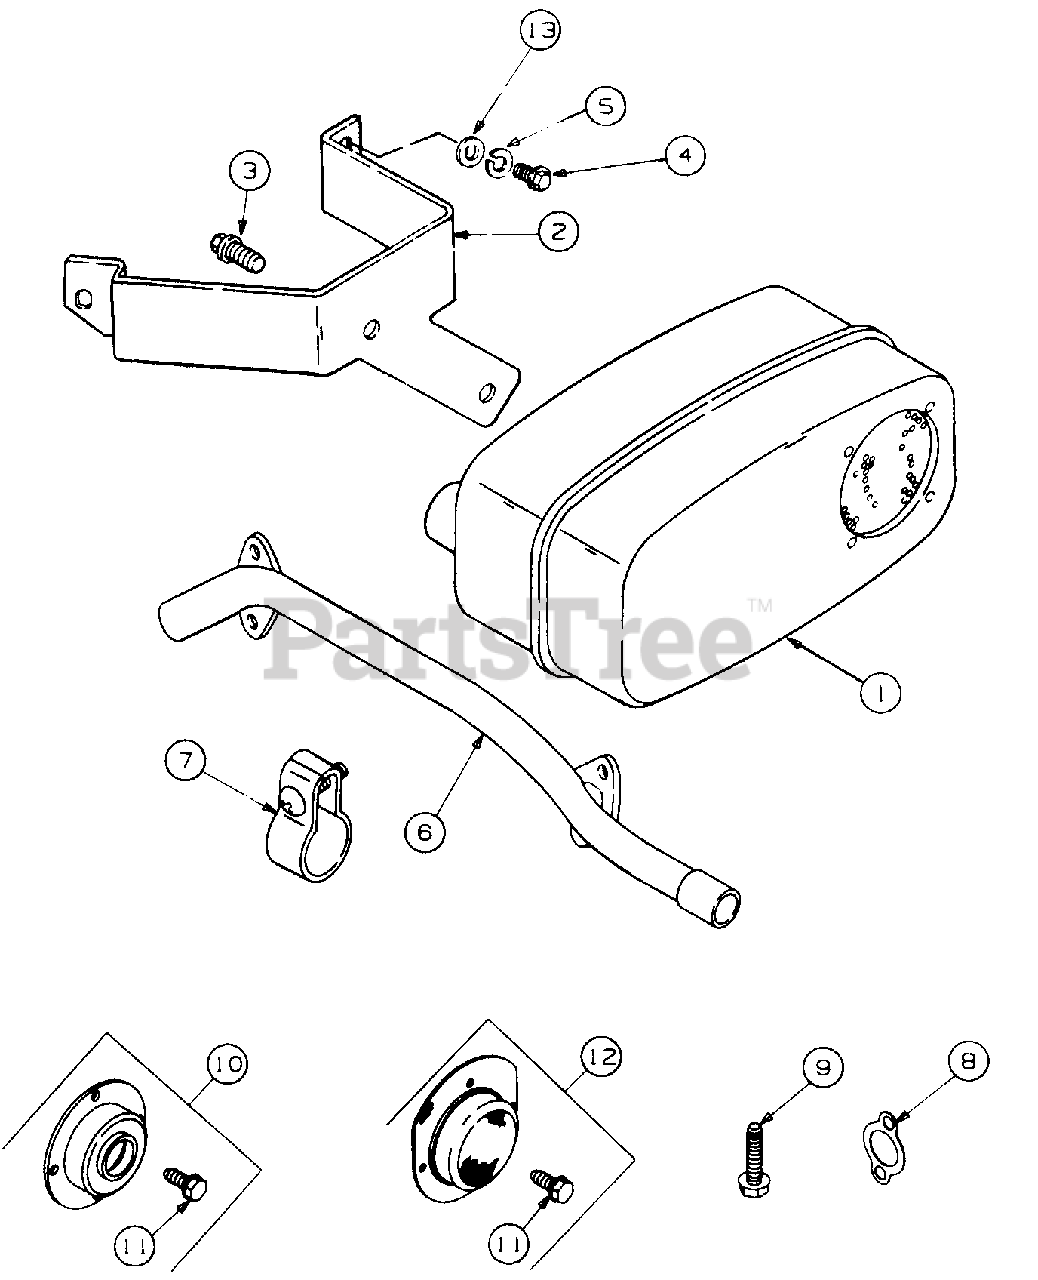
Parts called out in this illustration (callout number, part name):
1	Muffler
2	Bracket, Muffler
3	Screw, Hex Wash Hd Tap, 1/4-20 X .50 Lg
4	Screw, Hex Cap, M6-1.0 X 20 mm Lg GR10.9
5	Washer, Lock, 1/4
6	Manifold, Exhaust
7	Clamp, Muffler
8	Gasket, Exhaust Manifold
9	Screw, Sem
10	Deflector, Exhaust
11	Screw, Sem
12	Arrester, Spark
13	Washer, Flat, .281 X .75 X .105 Thk
